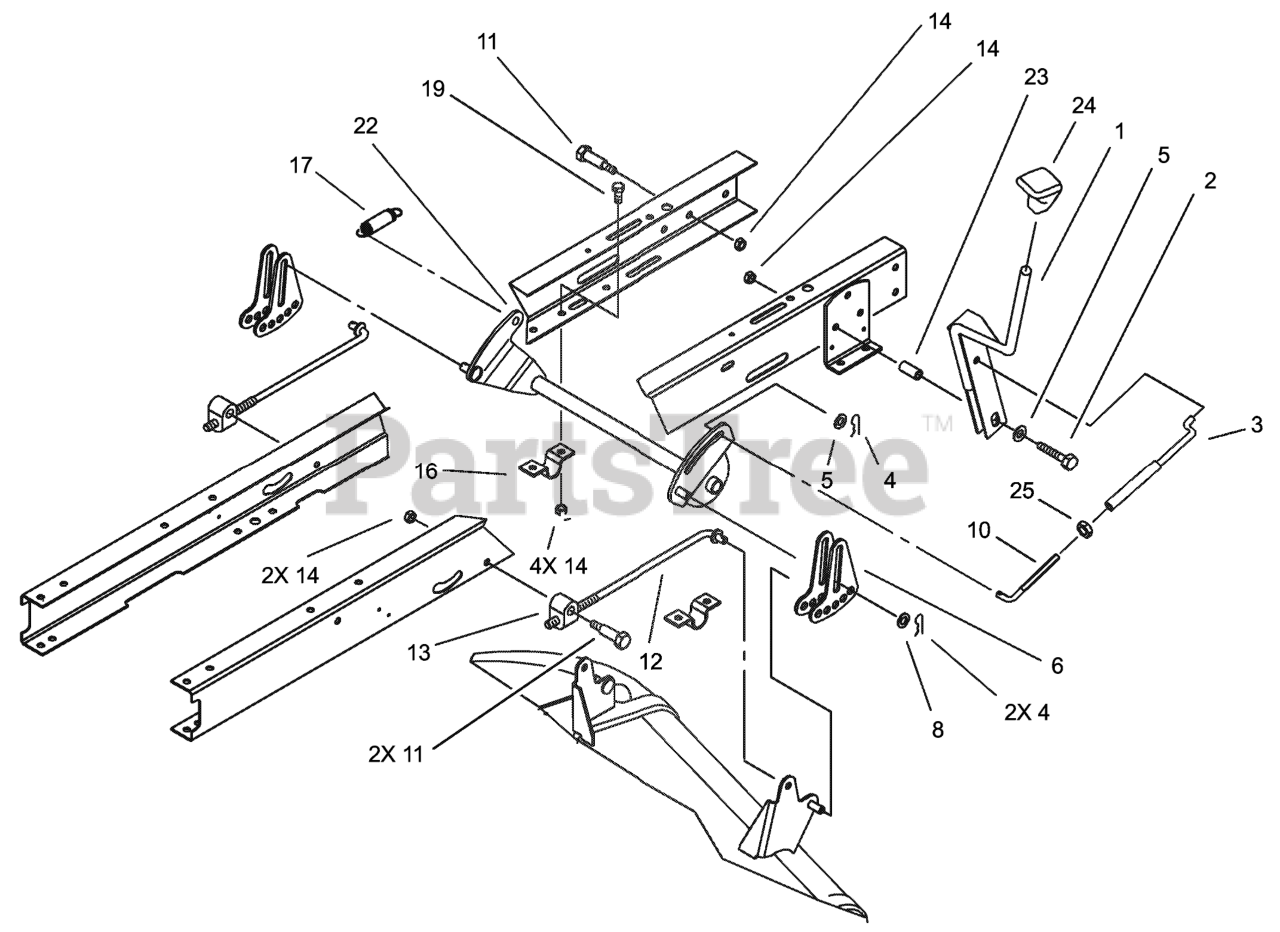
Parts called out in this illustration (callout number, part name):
1	HOC LEVER ASM
2	SCREW-HH
4	PIN-COTTER
5	WASHER-FLAT
6	LINK-ADJUSTING, HOC
8	WASHER-HARDENED
10	LINK-HOC
11	SCREW-SHOULDER, HH
12	ROD-HANGER, REAR
13	TRUNNION-HOC
14	NUT-LOCK, NI
16	CLAMP-PIVOT, HOC
17	SPRING-EXTENSION
19	SCREW-HH
22	PIVOT-HOC
23	SPACER
24	KNOB-SHIFT
25	NUT-JAM
